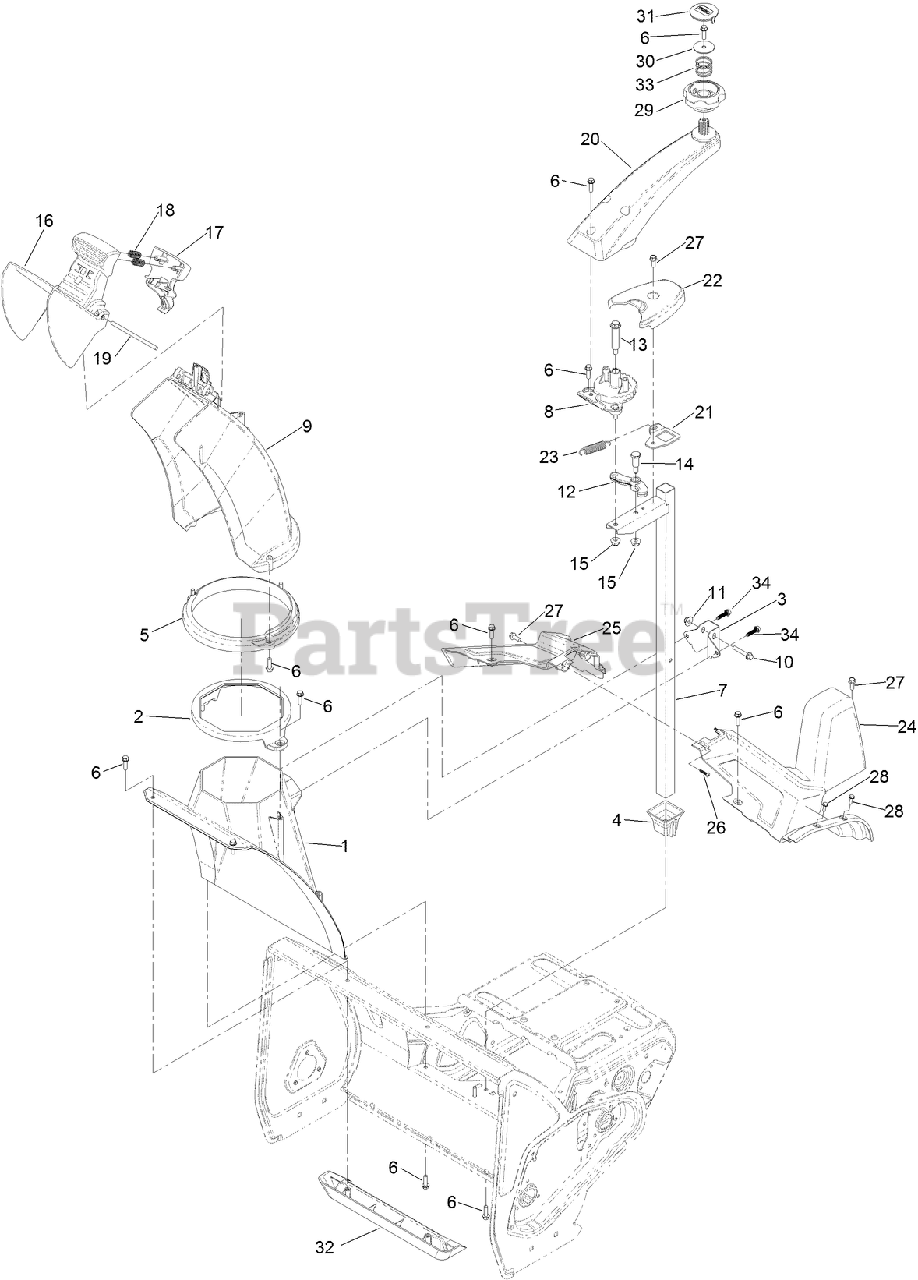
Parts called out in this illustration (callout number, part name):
1	CHUTE-LOWER
2	GUIDE-CHUTE
3	BRACKET-POST, SUPPORT (CHUTE)
4	RETAINER- POST, CHUTE
5	RING-CHUTE
6	SCREW-HWH
7	POST-CHUTE, MANUAL
8	GEAR-CHUTE, MANUAL
10	SCREW-HHF
11	NUT-HF
12	LATCH-CHUTE
13	BOLT-SHOULDER
14	SCREW-SHOULDER
15	NUT-HF, NI
16	DEFLECTOR-CHUTE
17	TRIGGER-DEFLECTOR
20	HANDLE-CHUTE, MANUAL
21	SUPPORT-SPRING
22	COVER-SPRING
23	SPRING-EXTENSION
24	SHROUD-UPPER, LH
25	SHROUD-LOWER, RH
26	SCREW-PPH
27	SCREW-HWH
28	SCREW-HWH
29	KNOB-CONTROL, CHUTE
30	WASHER-FLAT
31	INSERT-KNOB
32	KICKER-HOUSING
33	SPRING-COMPRESSION
34	SCREW-FLANGE, PLASTIC
